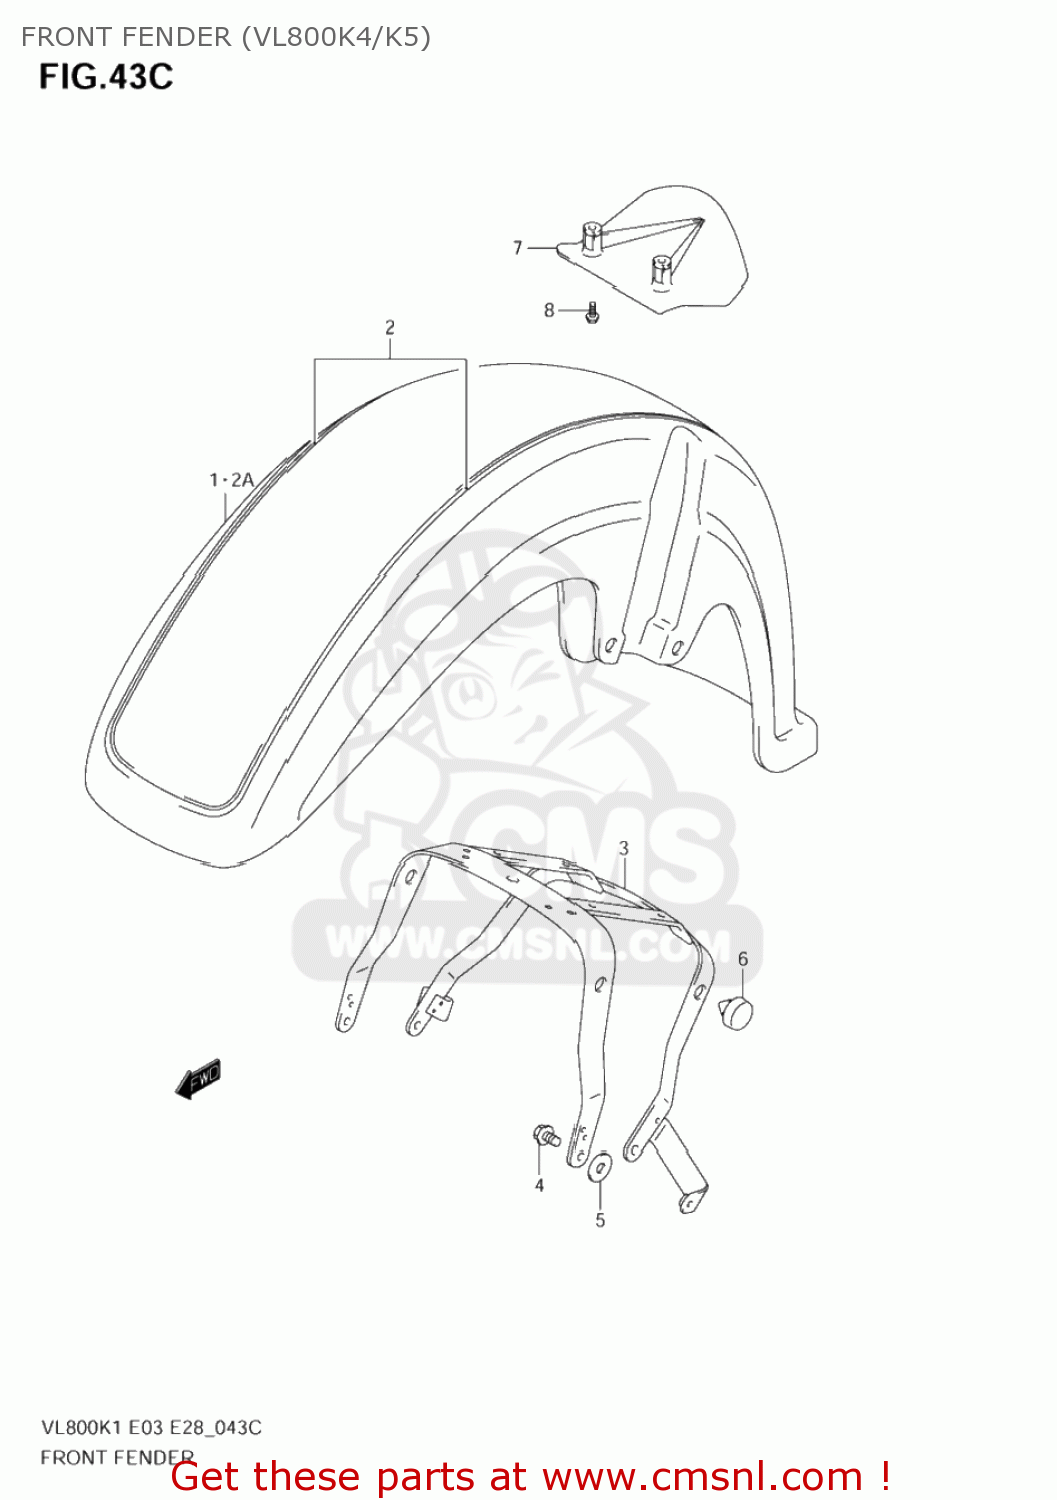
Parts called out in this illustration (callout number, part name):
1	FENDER,FR
2	TAPE SET,FR FENDER
2A	FENDER,FR
3	BRACE,FR FENDER
4	BOLT
5	WASHER,FR FENDER
6	CUSHION
7	WING,FR
8	BOLT(6X16)
